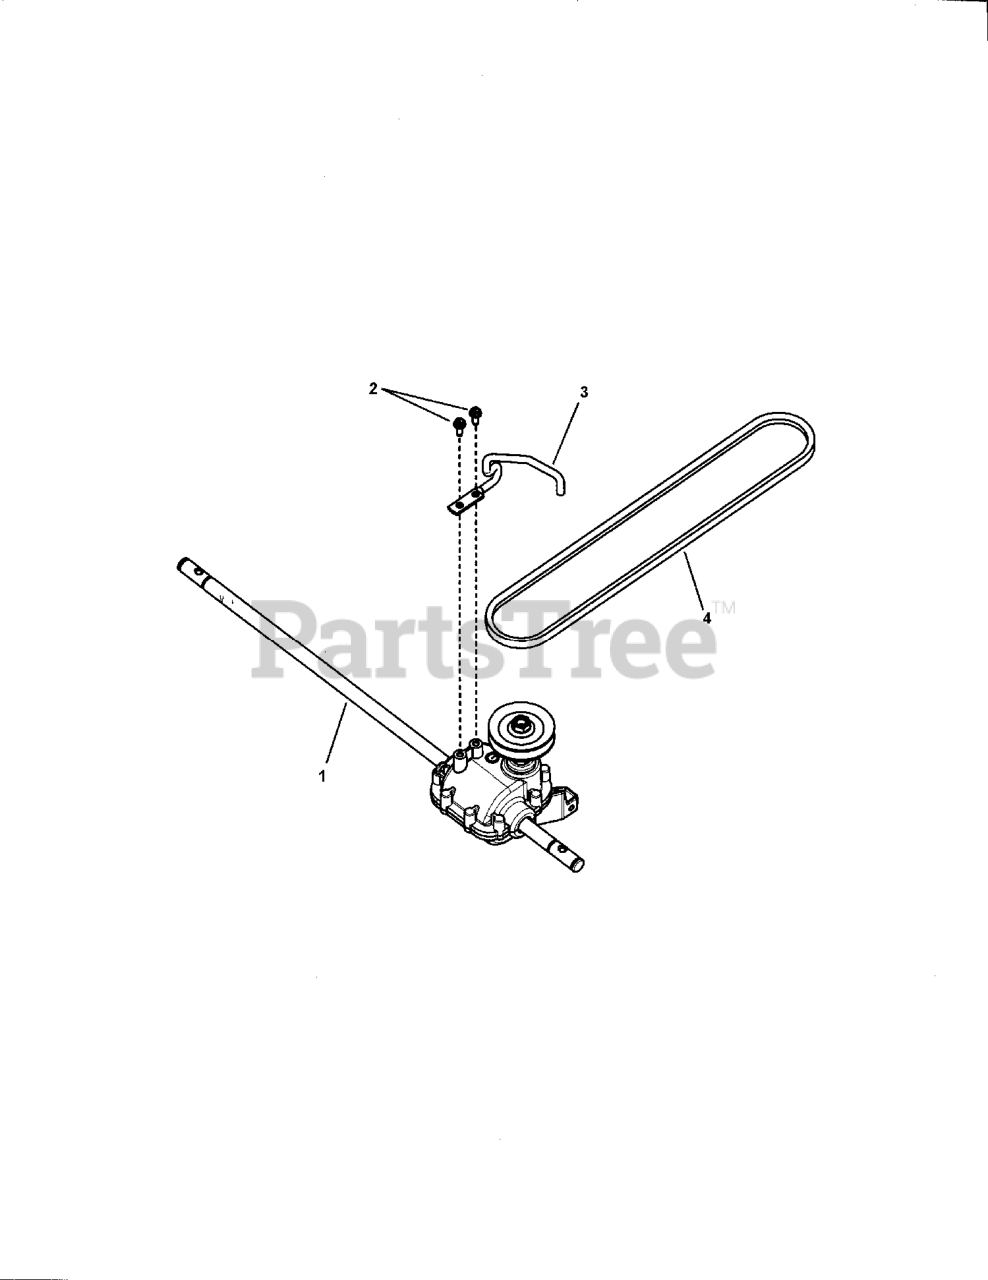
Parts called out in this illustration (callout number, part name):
1	TRANSMISSION, VS, FWD
2	HWST, PLASTITE 48-2, #10-14 X 1/2"
3	GUIDE, BELT, FWD
4	BELT, 3L, TRACTION DRIVE, 22" WBM, FWD
